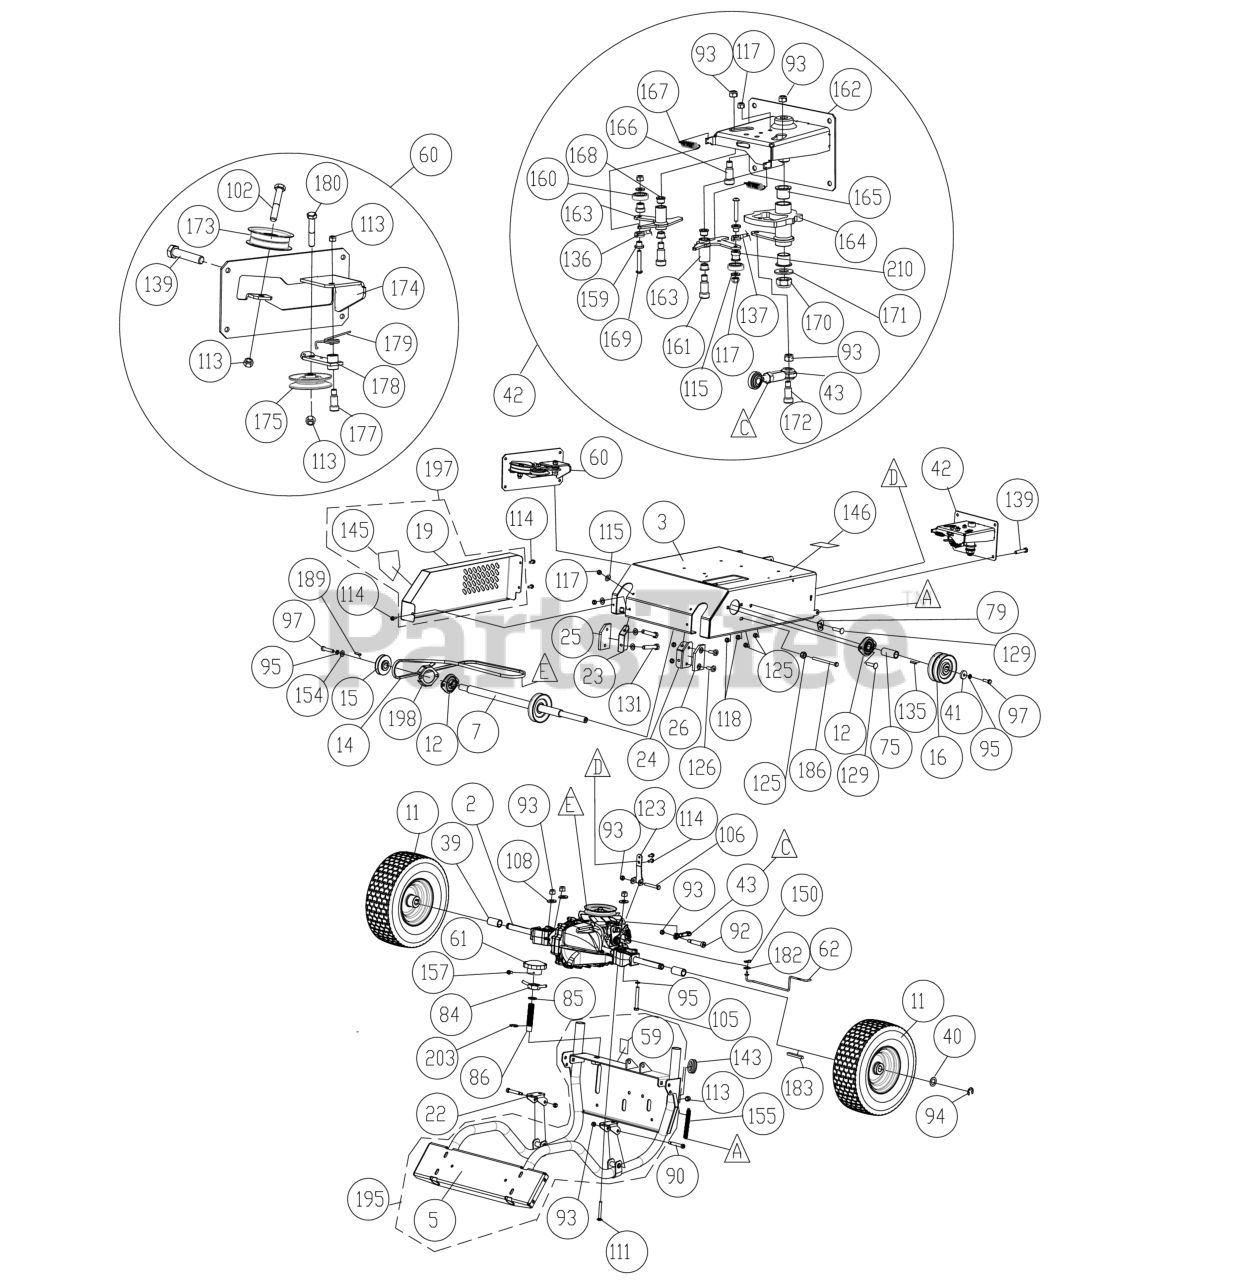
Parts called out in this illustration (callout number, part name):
2	TRANSAXLE
3	ENGINE BASE WA
5	FRAME SUPPORT OS900SP WA
7	JACKSHAFT WA
11	REAR WHEEL13" X 5" PNEU ASSY
12	BEARING & FLANGETTE ASSY .75"
14	BELT, TRUFLEX OS9 SERIES DRIVE
15	PULLEY 0.75 I.D. X 3.50
16	PULLEY 0.75" ID X 4" 4L SECTION
19	GUARD DRIVE BELT
22	BRACKET FIXED FRONT FRAME
23	BRACKET RH WEAR PAD
24	BRACKET LH WEAR PAD
25	WEAR PAD RH
26	WEAR PAD LH
39	SPACER REAR WHEEL
40	WASHER .765" ID X 1.25 OD X .06"
41	WASHER 1.125 OD X 0.344 ID X .25 THK ZP
42	SPEED CONTROL ASSY
43	CONNECTOR SPEED CONTROL
59	LABEL DEPTH GAUGE
60	MULE ASSY OS901SP
61	KNOB HAND
62	ROD, BYPASS ARM TRANSAXLE
75	SPACER PULLEY JACKSHAFT
79	BRACKET CLUTCH CABLE
84	LOCKNUT WA
85	WASHER 3\4" NYLON
86	STUD 3/4"-10 X 3 3/4 PLTD
90	BOLT SHOULDER 3/8" X 2"
92	BOLT SHOULDER 3/8" X 1/2"
93	NUT LOCK 5/16"-18 HEX Z/P
94	RING RETAINING "E" 3/4"
95	WASHER LOCK 5/16 ST MED
97	SCREWCAP 5/16"-24 X 1" GR.8 ZP W/PATCH
102	SCREWCAP 3/8"-16 X 1 3/4" HCS ZP
105	SCREWCAP 5/16"-18 X 3" HCS ZP
106	SCREWCAP 5/16"-18X2" HCS ZP
108	WASHER 5/16" FLATWASHER Z/P
111	BOLT CARRISGE 5/16-18 X 2 3/4" ZP
113	NUT LOCK 3/8"-16 HEX
114	SCREW SELF TAP 1/4"-20 X 5/8" HWH TYPE F
115	WASHER 1/4"SAE9/32"X5/8"X1/16"
116	WASHER 3/8"SAE 13/32"X13/16"X1/16"
117	NUT LOCK 1/4"-20 HEX Z/P
118	NUT FLANGE 5/16"-18 ZP
123	BRACKET TORQUE LIMITING
125	NUT FLANGE 5/16"-18 ZP
126	SCREW SPOT WELD 5/16"-18 X 3/4 W/PROJ
129	BOLT CARRIAGE 5/16"-18 X 3/4" ZP
131	SCREWCAP 1/4"-20 X 1" HCS ZP
135	KEY 3/16" SQ X 1 1/4"
136	SEE: 351219-S
137	SEE: 351271-S
139	SER HEX WASHER FLNG SCREW 5/16"-18 X 3/4"
143	GROMMET 1.25" HOLE
146	LABEL DRIVE RELEASE
150	PIN CLIP HITCH 0.051 X 3/4"
153	NUT LOCK 5/16"-18 LT WT TH ZP
154	WASHER FLAT FENDER 5/16
155	SPRING LIFT ASSIST
157	SCREW MACHINE #10-24 X 2" HWF ZP
159	SPACER, SPEED CONTROL EYELET PM
160	BEARING 1/2" ID X 1.125 OD
161	BOLT SHOULDER 3/8" X 1 3/4"
162	BRACKET SPEED CONTROL WA
163	BELLCRANK SPEED CONTROL WA
164	CAM SPEED CONTROL WA
165	BUSHING PIVOT FRAME AE
166	BOLT SHOULDER 5/16" X 1 1/2"
167	SPRING EXTENSION
168	BUSHING 3/8 ID X 1/2 OD X 3/8
169	SCREWCAP 1/4-20 X 1 3/4 SKT BUT HD
170	NUT LOCK 5/8"-11 LT WT TH Z/P
171	WASHER FLAT 5/8" SAE ZP
172	SCREWCAP 5/16"-18 X 1" HCS ZP
173	PULLEY IDLER 2.75" OD X 3/8" BORE
174	BRACKET DRIVE BELT WA
175	PULLEY 3V GROOVE IDLER
177	BOLT SHOULDER 1/2" X 2"
178	ARM IDLER MULE DRIVE WA OS900SP
179	SPRING, IDLER MULE DRIVE
180	SCREWCAP 3/8" - 16 X 1/2" HCS ZP
182	WASHER #10SAE 7/32"X1/2"X1/16"
183	KEY 3/16" SQ X 2 1/8"
186	SCREWCAP 5/16"-18 X 5" HCS ZP
189	KEY 3/16" SQ X 5/8"
195	FRAME SUPPORT OS901SP W/LABELS
197	DRIVE BELT GUARD WA W/LABELS
198	BRACKET, BELT GUIDE OS901SP
203	RING SNAP TRUARC 5/8"
210	SPACER. SPEED CONTROL STEPPED PM
